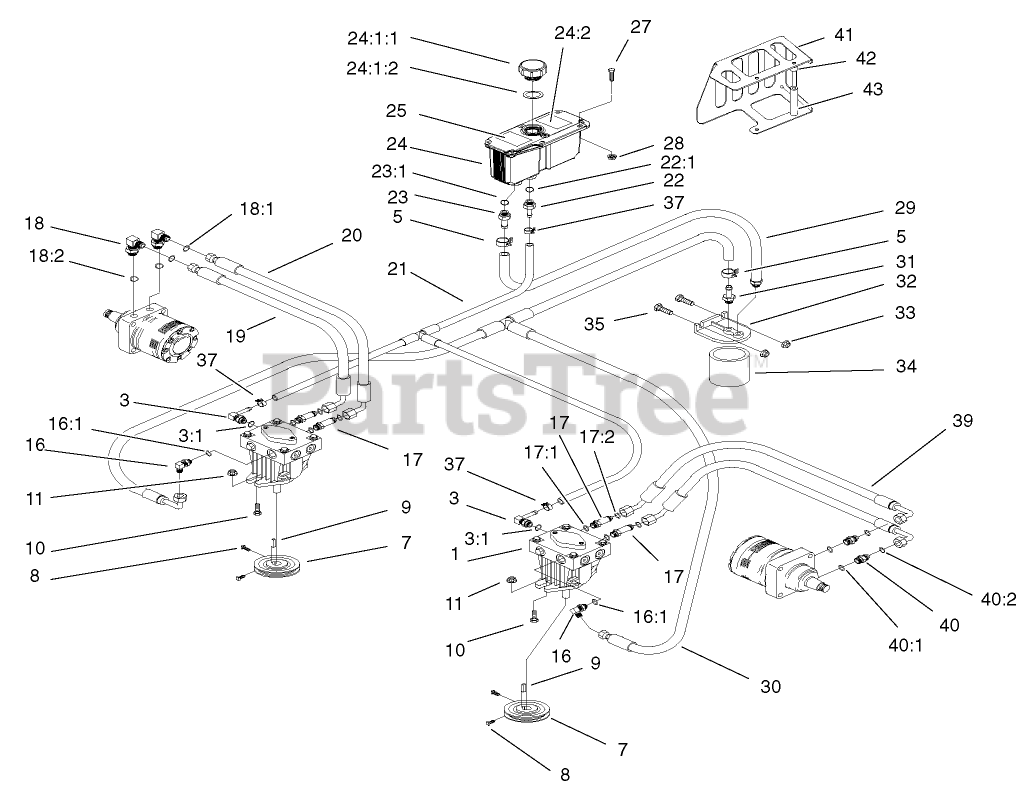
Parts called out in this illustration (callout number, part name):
1	PUMP-HYD
3	ELBOW-90 DEG
3:1	O-RING
5	Clamp-Hose
7	PULLEY
8	SCREW-SET
10	SCREW-HH
11	NUT-HHF, WHIZ
16	FITTING-ELBOW, 90 DEG
16:1	O-RING
17	ADAPTER-HYD, STRAIGHT
17:1	O-RING
17:2	O-Ring
18	FITTING-HYD, 90 DEG
18:1	O-Ring
18:2	O-RING
19	HOSE-FRONT
20	HOSE-REAR
21	HYD Hose ASM
22	Adapter-Straight
22:1	O-RING
23	ADAPTER-STRAIGHT
23:1	O-RING
24	Hydraulic Tank ASM
24:1	HYD Reservoir ASM
24:1:1	CAP-RESERVOIR, HYD
24:1:2	GASKET-CAP
24:2	DECAL-HOT SURFACE
25	DECAL-EXHAUST
27	SCREW-HH
28	NUT-HF
29	HYD Hose ASM
30	HYD Hose ASM
31	Adapter-Straight
32	HEAD-FILTER
33	NUT-HF
34	FILTER-OIL, HYD
34	FILTER-OIL, HYD (WINTER)
35	SCREW-HH
37	Clamp-Hose
39	HOSE ASM
40	Fitting-Straight
40:1	O-RING
40:2	O-Ring
41	Shield-Heat, HYD Reservoir
42	Spacer
43	Spacer
